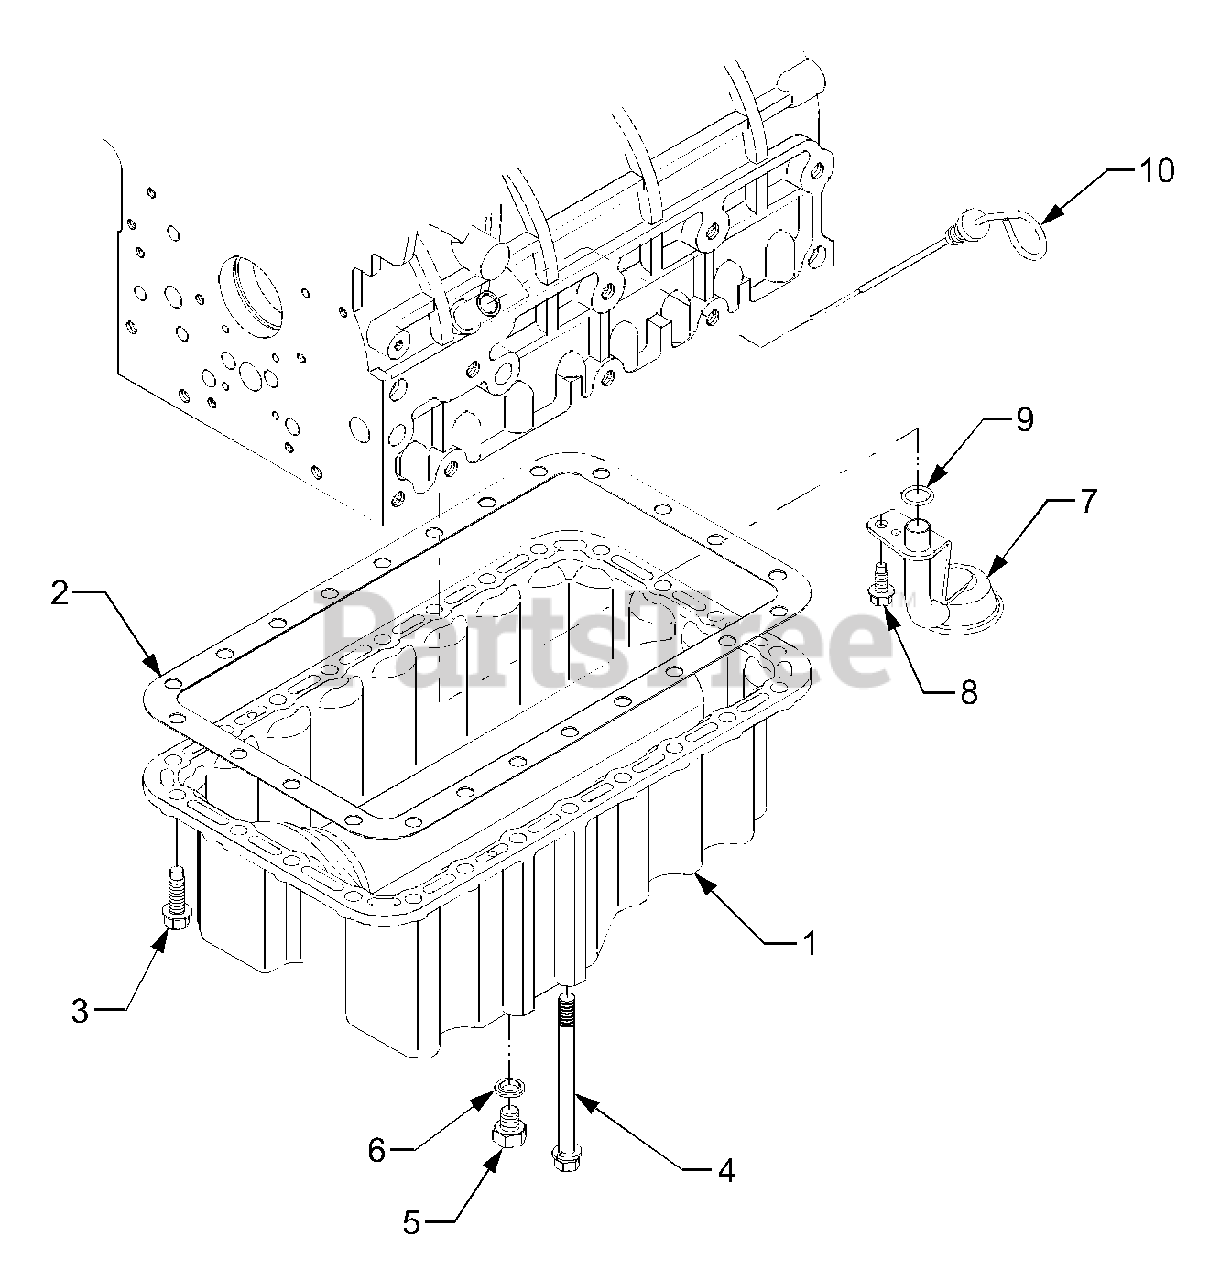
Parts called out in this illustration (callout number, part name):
1	Oil Pan Ass'y
2	Gasket, Oil Pan
5	Plug, Drain
7	Filter 1, Oil
10	Gauge, Oil
